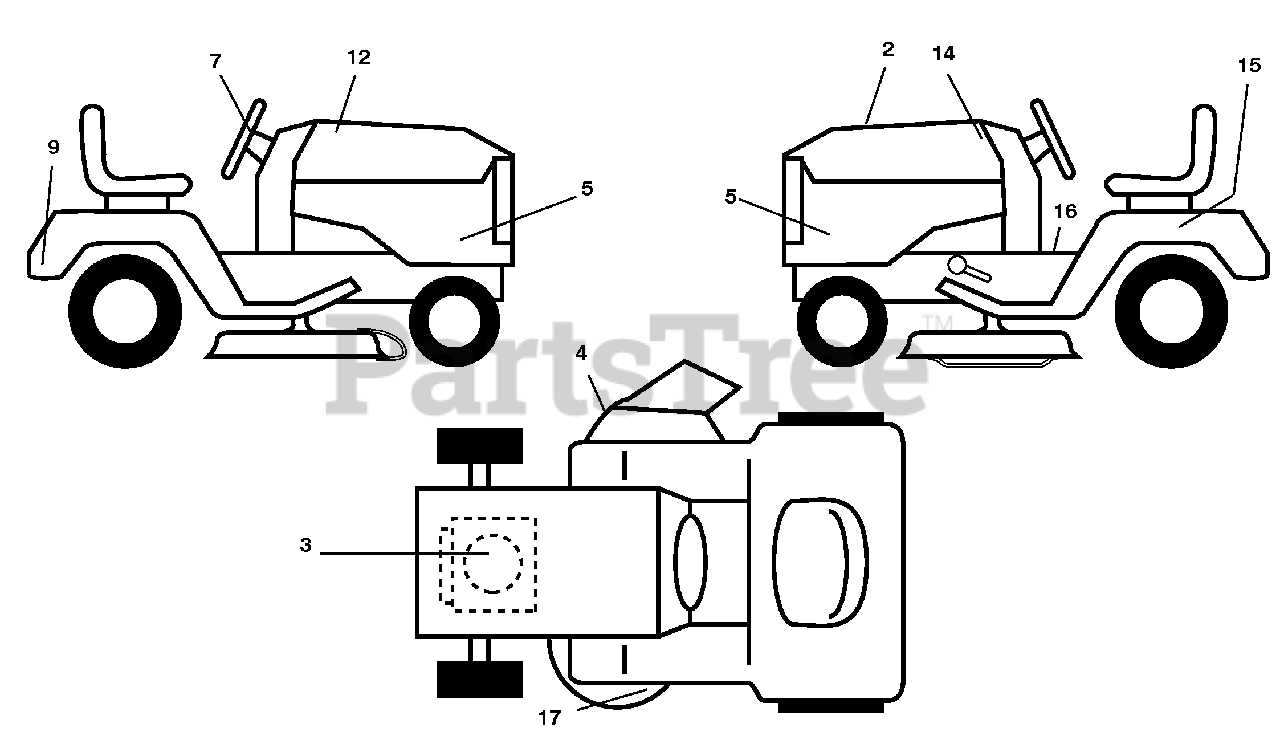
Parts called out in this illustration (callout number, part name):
2	Decal, Replacement
3	Decal, Engine HP
4	Decal, Warning
5	Decal, SDPNL
7	Decal, Ins Str Wh
9	Decal, Fender
12	Decal, Hood RH
14	Decal, Hood LH
15	Decal, Caution, Battery
16	Decal, Fender Warning Eng/Fr
17	Decal, V-Belt Sch.
17	Decal, Handle Lft Height Adj.
17	Manual, Operator's E&F
17	Manual, Parts E&F
